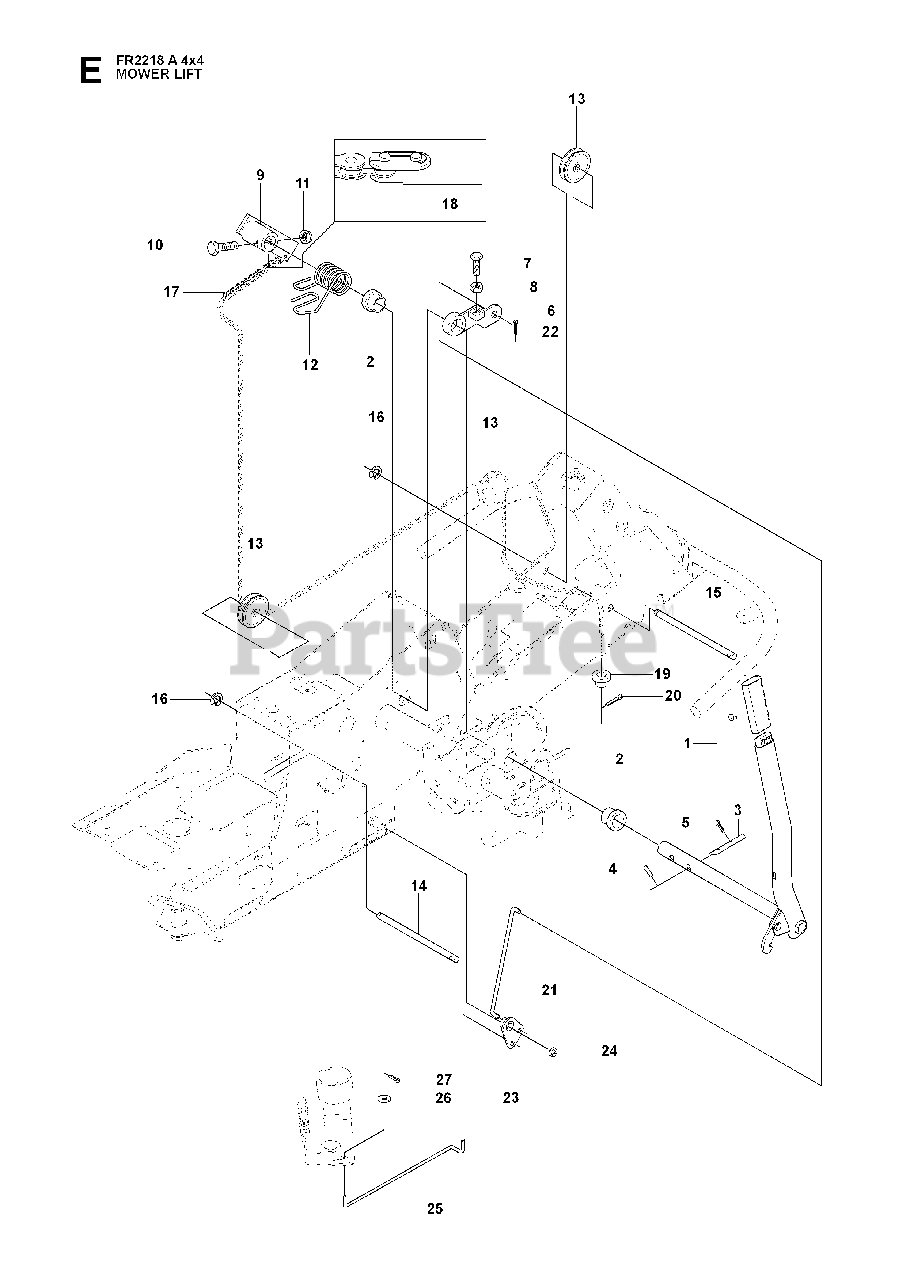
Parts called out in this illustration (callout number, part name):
1	LIFTING LEVER ASSY
2	BUSH
3	RP PIN
5	SPLIT PIN
6	LEVER CLUTCH
16	LOCK RING
20	COTTER PIN
21	CONNECTION ROD
22	SPLIT PIN
24	RETAINING RING
25	CONNECTION ROD
27	SPLIT PIN
